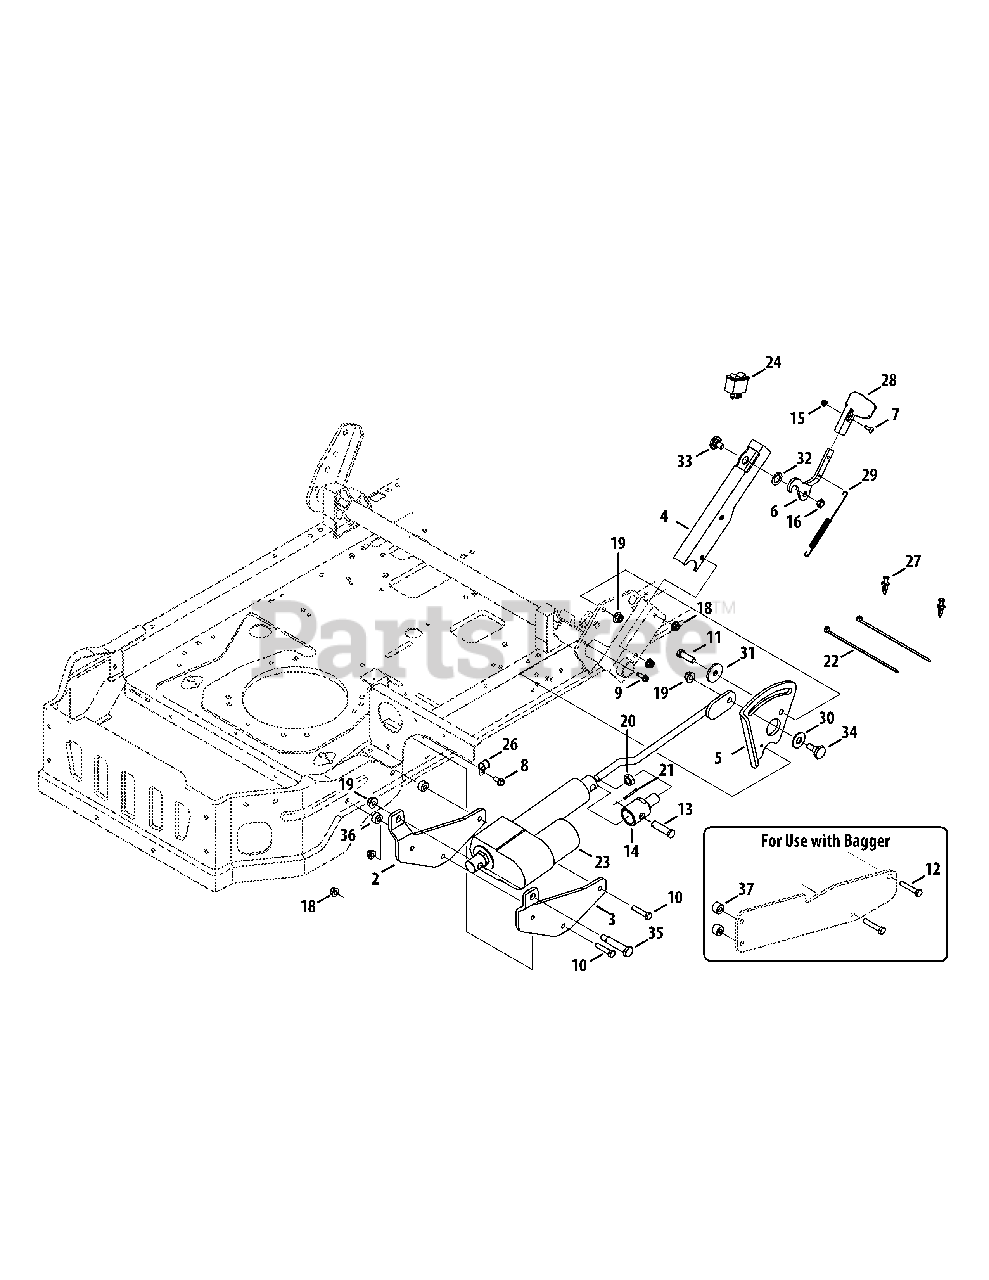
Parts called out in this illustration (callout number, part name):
1	Link Assembly, Lift
2	Bracket, Mounting, Inner
3	Bracket, Mounting, Outer
4	Handle, Lift, Electric
5	Bracket, Lift, Electric, RH
6	Bracket, Lock, Lift
7	Screw, Machine, #10-24, 0.625
8	Screw, Self-tapping, 5/16-18, .750
9	Screw, Self-tapping, 1/4-20, .750
10	Hex Screw, 5/16-18, 1.50
11	Hex Screw, 3/8-16, 1.25
12	Hex Screw, 5/16-18, 1.75
13	Pin, Clevis, .50 Dia x 1.59
14	Coupling, Lift, Actuator
15	Nut, Hex Lock, #10-24, Nylon
16	Nut, Jam, 3/8-16, Gr5
17	Nut, Sems, 1/4-20
18	Nut, Flange Lock, 5/16-18, Nylon
19	Nut, Flange Lock, 3/8-16, Nylon
20	Nut, Jam, 1/2-13, Gr5
21	Pin, Cotter, 1/8 x 1.0
22	Cable Ties
25	Harness, Electric Deck Lift
27	Rivet, Plastic
29	Spring, Extension, .38 Dia x 5.6
30	Washer, Flat, .531 x 1.25 x .100
31	Washer, Flat, .390 x 1.50 x .134
32	Washer, Flat, .634 x 1.00 x .04
33	Screw, Shoulder, .625 x .17, 3/8-16
34	Screw, Shoulder, .500 x .434
35	Screw, Shoulder, .498 x 2.045
36	Spacer, .315 x .75 x .375
37	Spacer, .325 x .75 x .520
